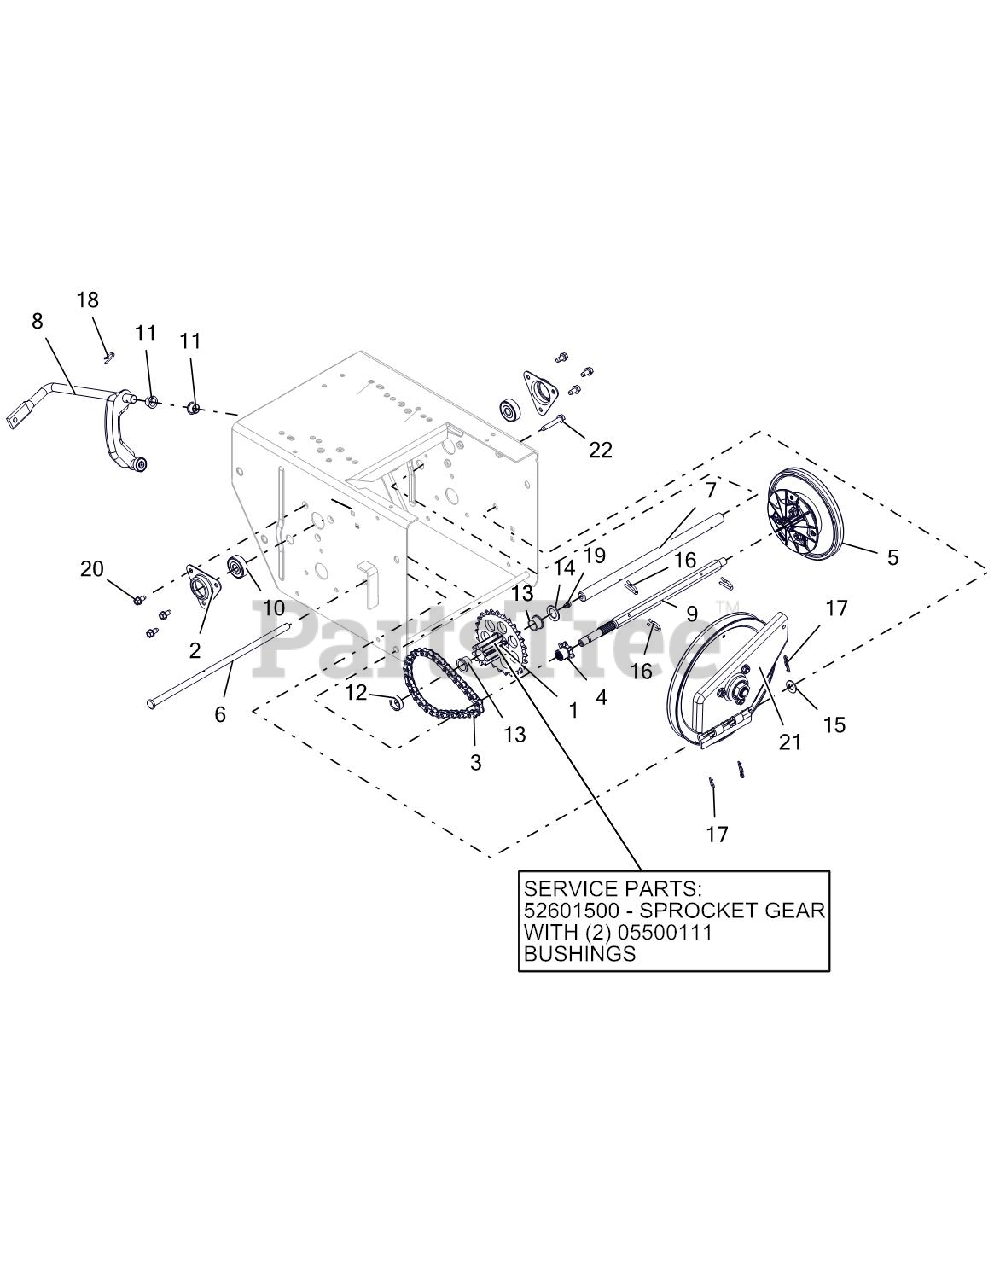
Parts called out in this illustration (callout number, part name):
1	BSHG-FLG .625X.750X.500X.875
1	PINION & SPROCKET
1	PINION & SPROCKET W/BUSHINGS
2	FLANGE, BEARING
3	CHAIN - #41, 32 PITCHES
4	SPROCKET, PINION 7T W/SPLINE
5	DISC, FRICTION DRIVE-ASSEMBLY
6	PIN, PIVOT
7	SHAFT, PINION-HARDENED
8	ARM, SHIFT - ASSEMBLY
9	SHAFT, HEX - HEAT TREATED
10	BRG-BALL .437X1.375X.437
11	BUSHING, POLYLINER-.50 SPLIT
12	BSHG-SLV, .635X.880X.305
13	BSHG-FLG .625X.750X.500X.875
14	WSHR-FL-STL .630X1.005X.062 YZ
15	@WSHR-FL-STL.406X.812X.065 YWZ
16	PIN, SPRING CLIP
17	PIN-HAIR, ENDRIES #25 YWZC
18	CLIP, SPRING
19	ZERK,FITTING .25X.125 DRIVE IN
20	SCR-TAP .25-20X.50 HWH TR YWZ
21	PLATE, SWING ASSEMBLY-DEEP
22	@SCR-TAP .25-20X1.50 HWH TR YZ
